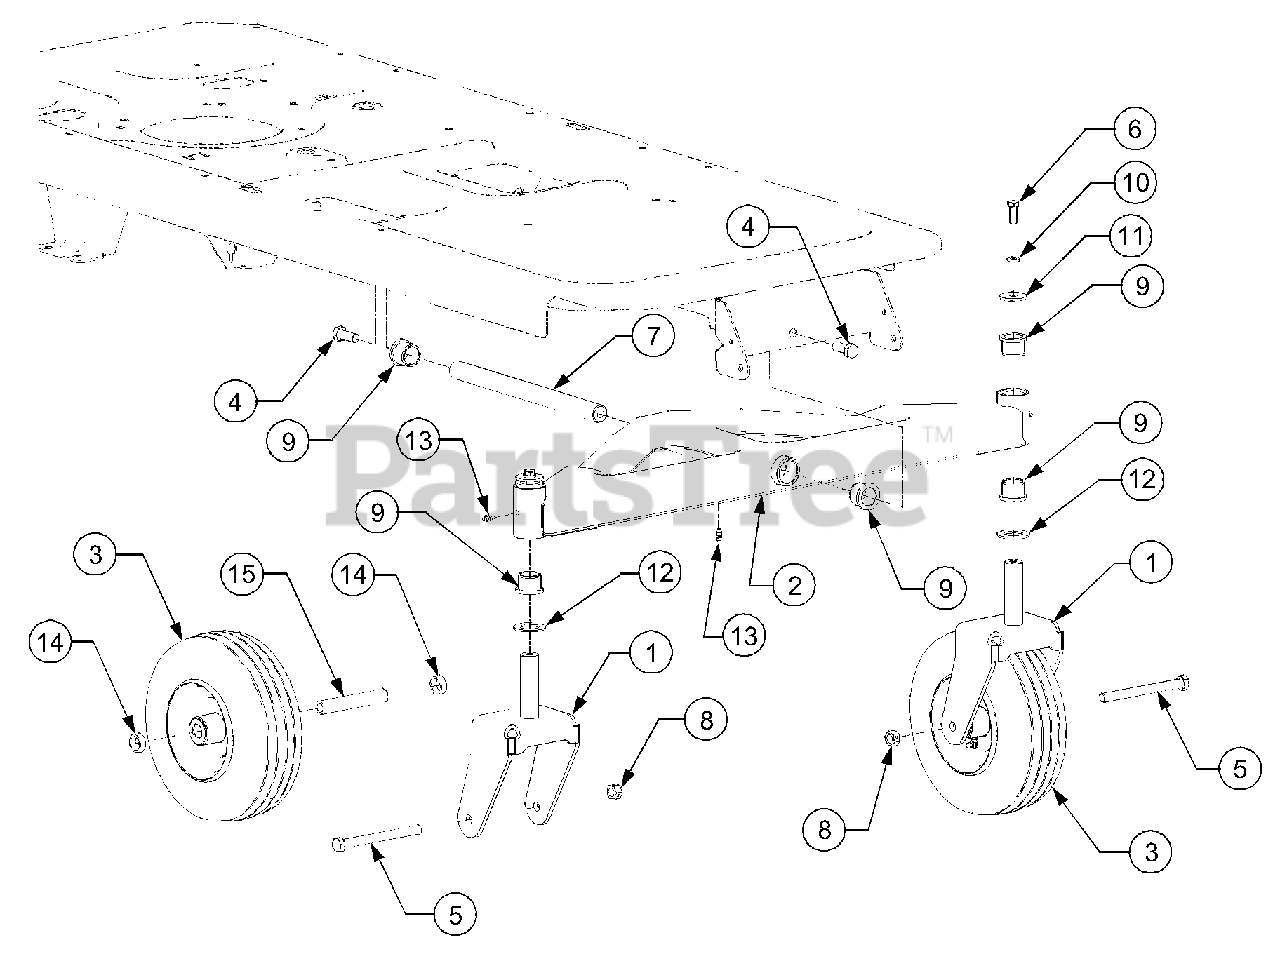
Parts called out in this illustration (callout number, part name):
3	Wheel Assembly, 11.0 x 4.0 x 5.0
4	Screw, Hex Lock, 1/2-13 x 1.25 GR5
5	Screw, Hex Cap, 1/2-20 x 5.5 GR5
6	Screw, Hex Cap, 3/8-16 x 1.0 GR5
7	Shaft, Axle
8	Nut, Hex Lock, 1/2-20 GRA
9	Bearing, Flange, 1.0 x 1.254
10	Washer, Lock, 3/8
11	Washer, Flat, .39 x 1.5 x .134
12	Washer, Flat, 1.0 x 1.75 x .107
13	Fitting, Lube, 3/16 Drive
14	Spacer, .79 x .347
15	Spacer, Wheel
